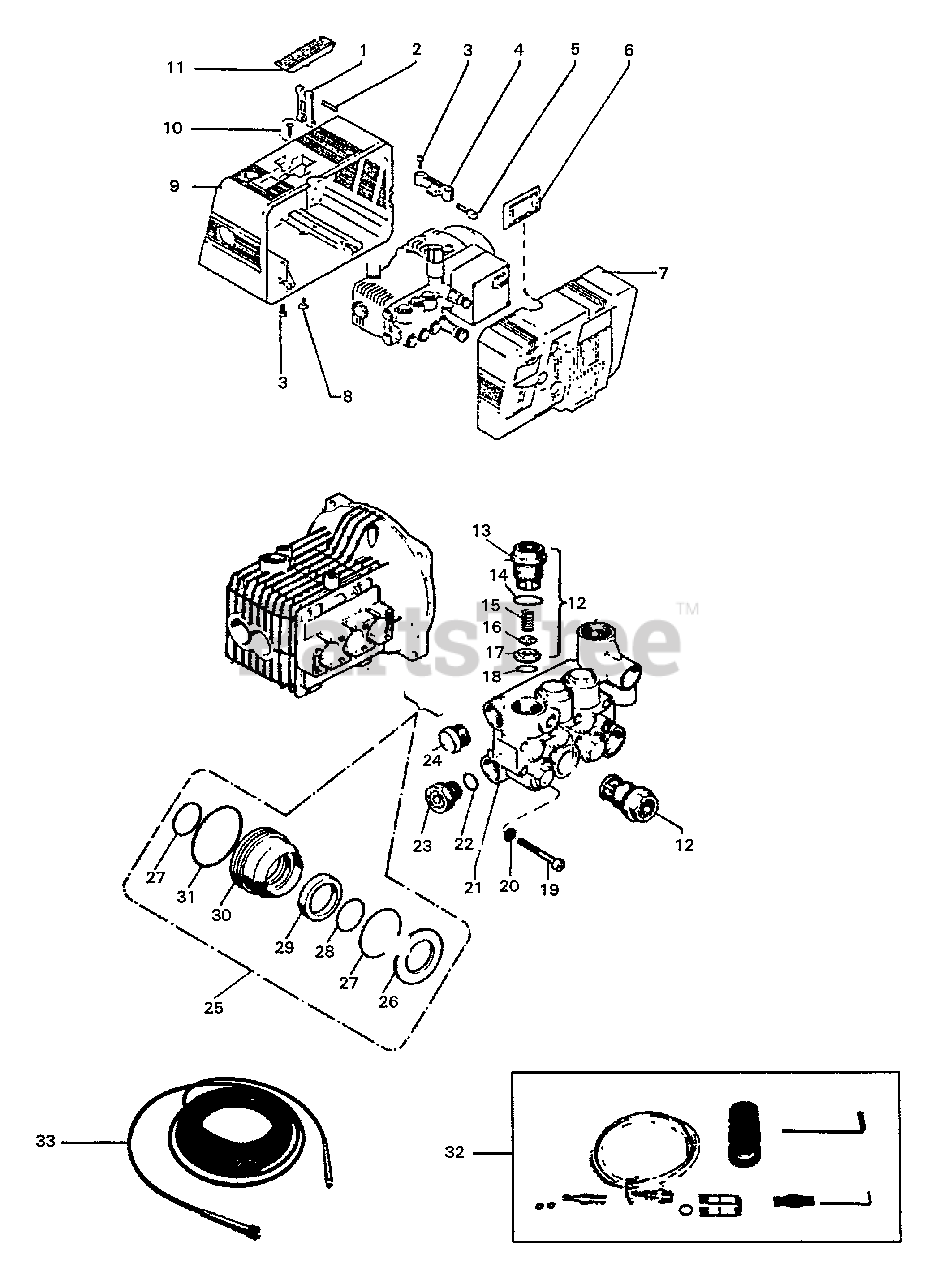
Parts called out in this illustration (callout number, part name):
1	ARM, HANDLE
2	PIN
3	SCREW M8×16
4	PLATE, HANDLE RETAINER
5	SHAFT
6	SWITCH, IGNITION
7	COVER, FRONT
8	PLUG
9	COVER, REAR
10	SCREW - 4×13
11	HANDLE
12	VALVE KIT
13	CAP, VALVE
14	O-RING
15	SPRING, VALVE
16	PLATE
17	SEAT, VALVE
18	O-RING
19	SCREW M6×40
20	LOCKWASHER - 6
21	MANIFOLD
22	O-RING
23	PLUG
24	CAP
25	RETAINER REBUILD PACKING KIT
26	WASHER
27	O-RING
28	O-RING
29	PACKING
31	O-RING
32	ACCESSORY KIT
33	HOSE - 8M
